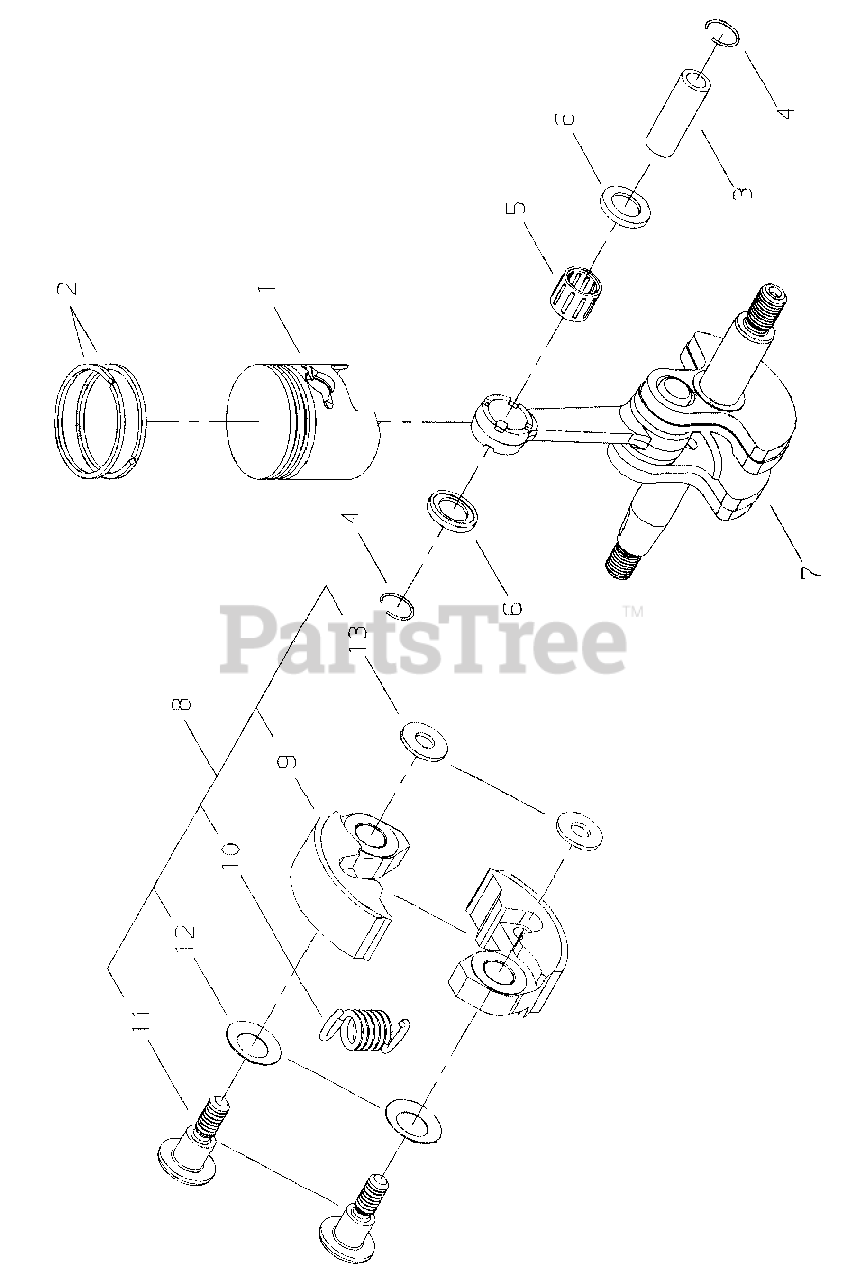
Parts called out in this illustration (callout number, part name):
1	PISTON
2	RING, PISTON
3	PIN, PISTON
4	RING, RETAINING
5	BEARING, NEEDLE
6	SPACER, PISTON
7	CRANKSHAFT
8	CLUTCH ASSY
9	CLUTCH SHOE SET
10	SPRING, CLUTCH
11	BOLT, CLUTCH
12	WASHER - SPRING
13	WASHER - 6
